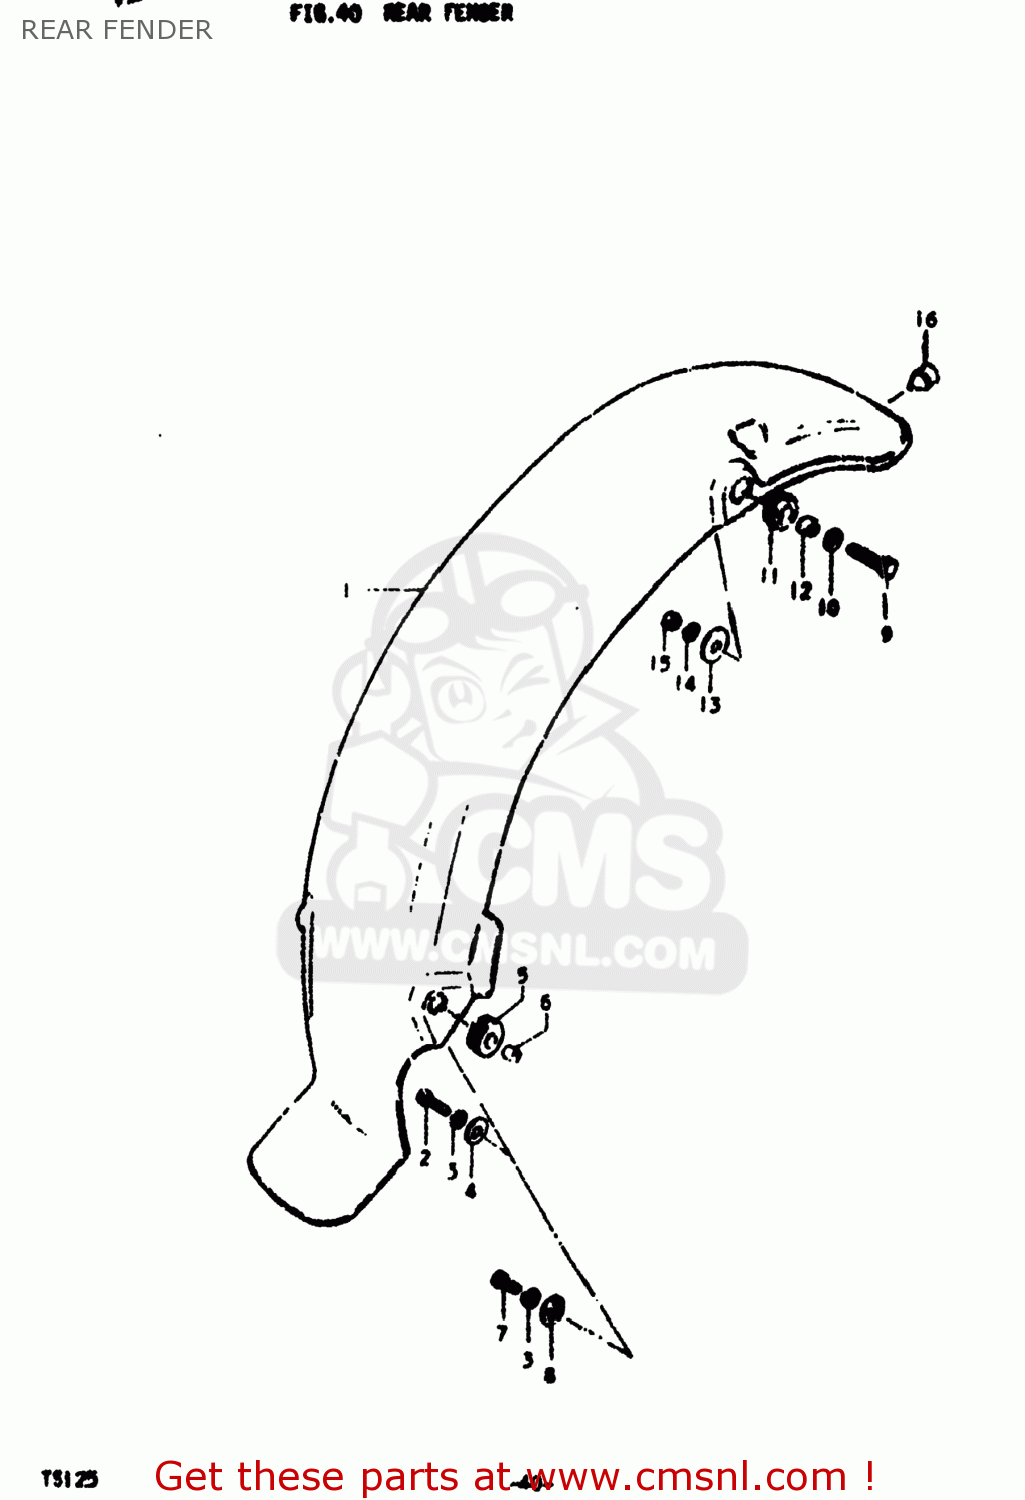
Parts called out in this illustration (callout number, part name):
1	FENDER,REAR
2	BOLT
3	LOCK WASHER
4	WASHER (6.5X20X1.2)
5	CUSHION
6	SPACER (6.3X9.1X6.7)
7	BOLT, UPPER
8	WASHER
9	BOLT ,6X35
10	WASHER
11	CUSHION
12	WASHER (8.2X24X1.6)
13	WASHER(8.5X26X1.2)
14	LOCK WASHER
15	NUT
16	CUSHION
